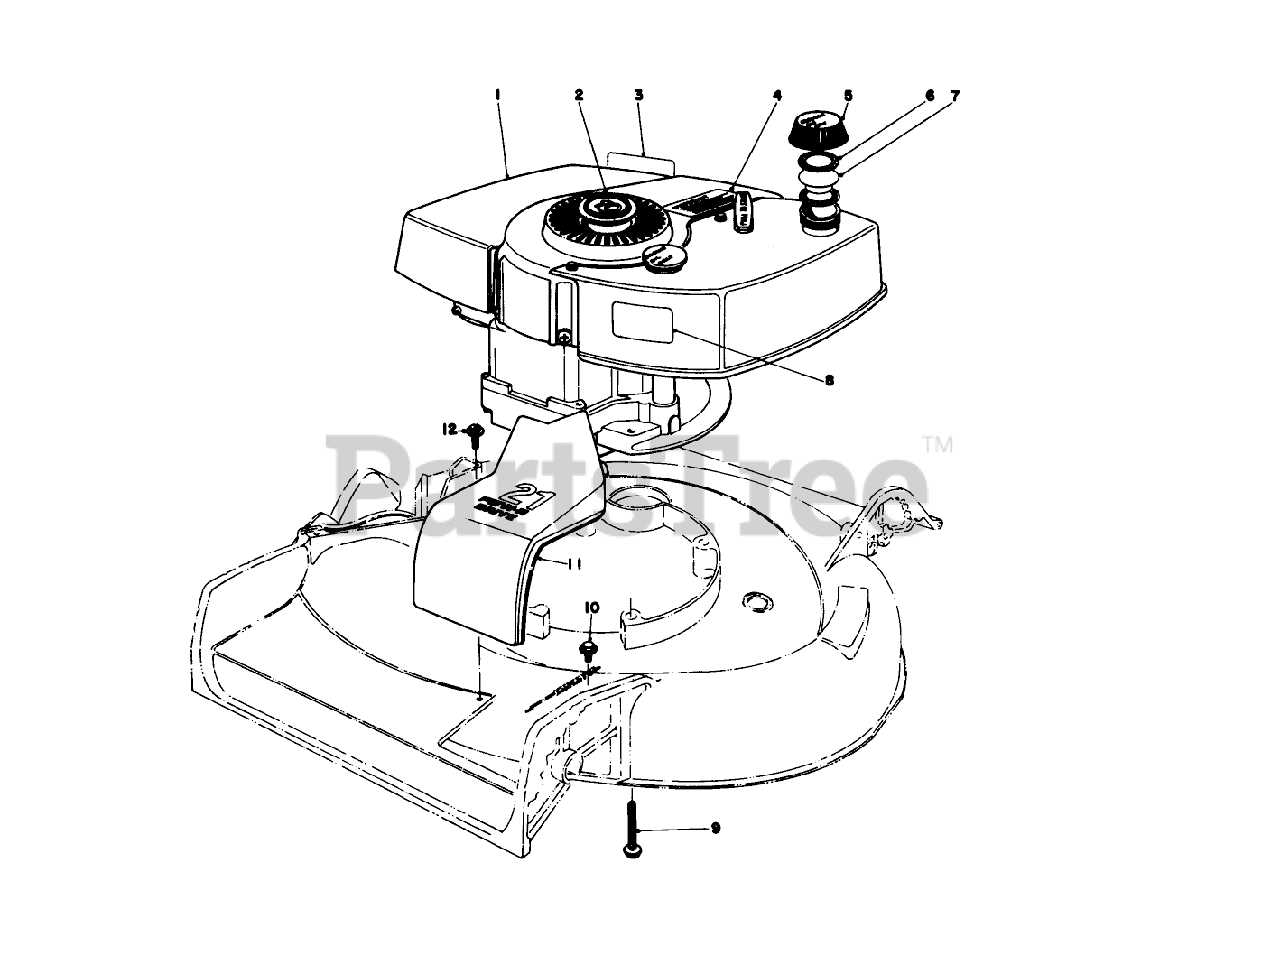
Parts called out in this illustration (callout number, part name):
1	Engine
2	PLUG BUTTON
3	Decal Maintenance
4	Decal Lockout
5	Gas Cap (Incl. Ref. #6 & 7)
6	GASKET
7	GAS CAP BAFFLE
8	Decal
9	3/8-16 X 2-3/4 CAPSCR
10	SCREW-HWHTF
11	Cover Belt Drive
12	SCREW
